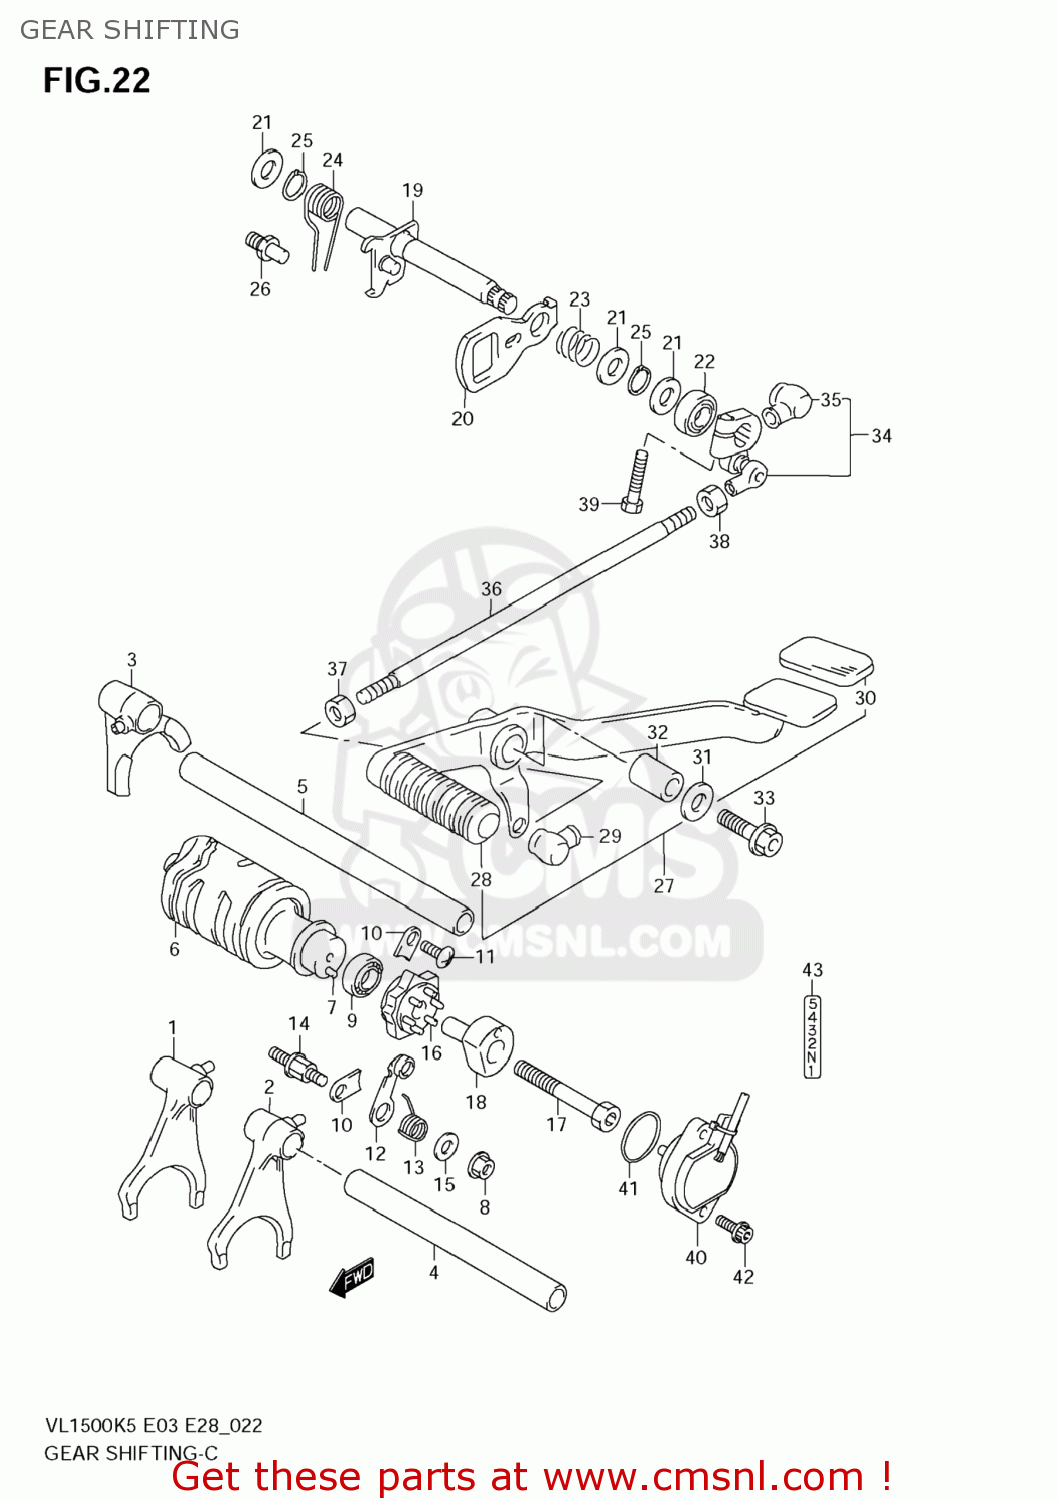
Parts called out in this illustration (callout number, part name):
1	FORK,GEAR SHIFT NO.1
2	FORK,GEAR SHIFT NO.2
3	FORK,GEAR SHIFT NO.3
4	SHAFT,GEAR SHIFT FORK NO.1
5	SHAFT GEAR SHIFT FORK NO.2
6	CAM,GEAR SHIFT
7	PIN
8	NUT
9	BEARING(25X47X8)
10	RETAINER,BEARING
11	SCREW
12	STOPPER,GEAR SHIFT CAM
13	SPRING,STOPPER ARM
14	SUPPORT,CAM STOPPER ARM
15	WASHER
16	PLATE,GEAR SHIFT CAM
17	BOLT(6X50)
18	HOLDER,NEUTRAL SWITCH
19	SHAFT,GEAR SHIFT
20	PLATE,GEAR SHIFT CAM DRIVE
21	SHIM(14X22X1)
22	SEAL,OIL(14X22X6)
23	SPRING
24	SPRING
25	CIRCLIP
26	STOPPER,GEAR SHIFT ARM
27	LEVER ASSY,GEAR SHIFT
28	RUBBER
29	COVER,DUST
30	RUBBER,BRAKE PEDAL
31	WASHER (10.5X24X2.3)
32	SPSCER,GEAR SHIFT LEVER
33	BOLT(10X40)
34	ARM,GEAR SHIFT LINK
35	COVER,DUST
36	ROD,GEAR SHIFT LINK
37	NUT
38	NUT
39	BOLT
40	SENSOR ASSY,GEAR POSITION
41	O RING(D:2.4,ID:35.5)
42	BOLT
43	LABEL,GEAR SHIFT
